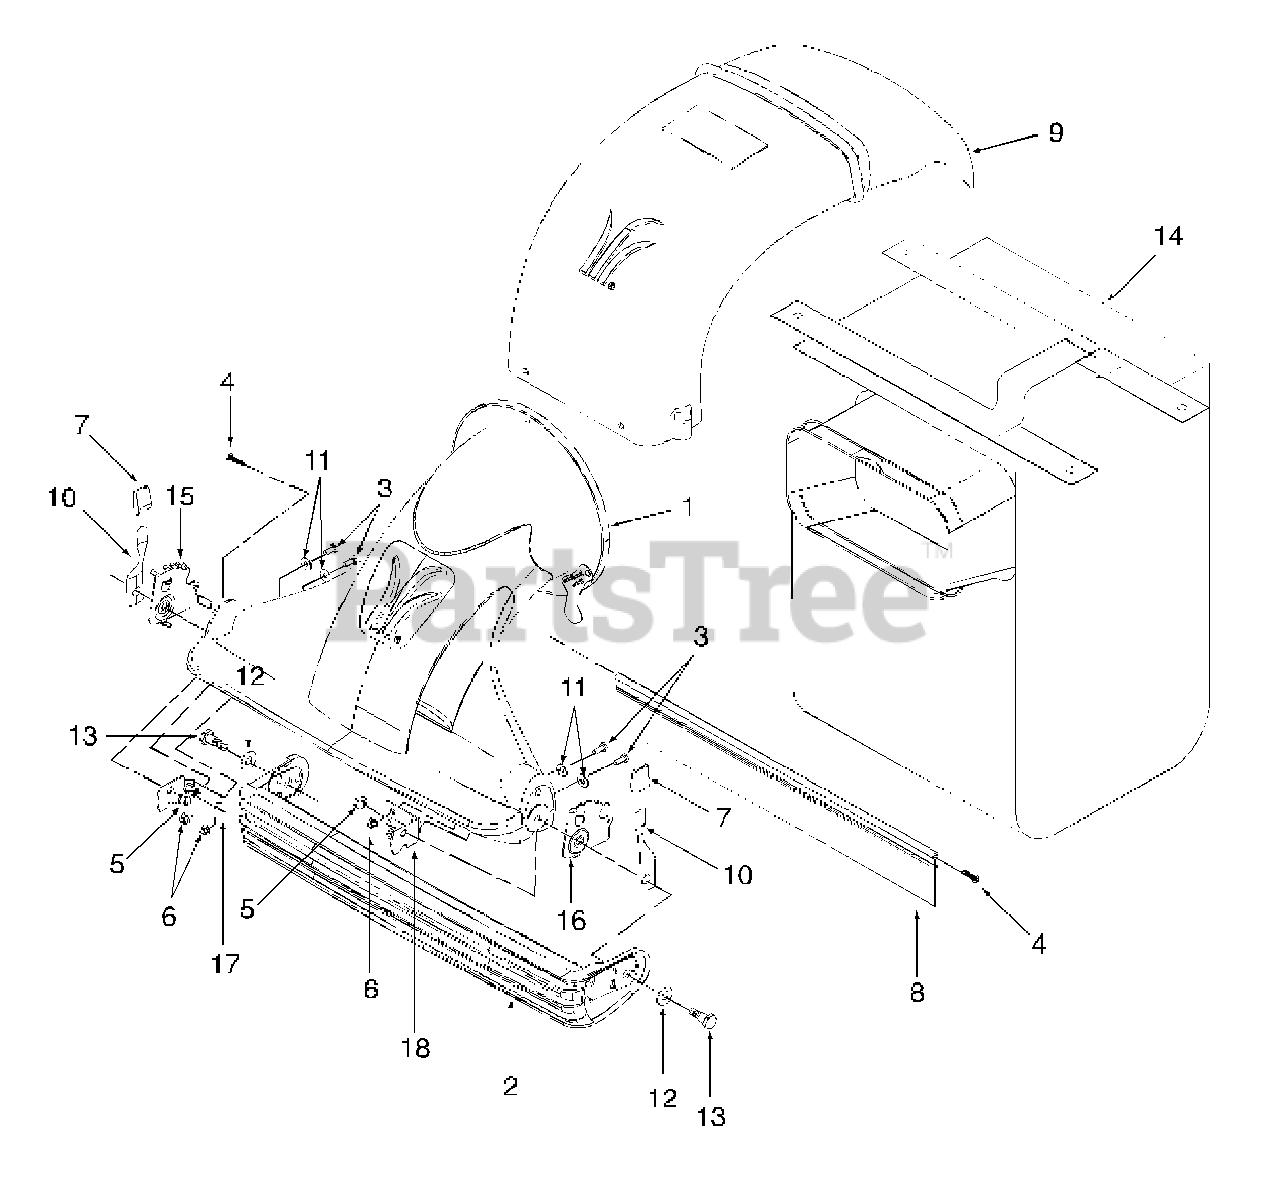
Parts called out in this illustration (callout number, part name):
1	Nozzle Assembly, Black
2	Door Assembly, Black
3	Screw, Hex Cap, 1/4-20 x .625
4	Screw, Truss Hd Tapp
5	Nut, Hex Flange Lock, 3/8-16
6	Nut, Hex Flange Lock, 1/4-20
7	Knob, Height Adj.
8	Flap, Nozzle Rear
9	Discharge Chute
10	Spring Lever
11	Washer, Flat, .28 x .74 x .06
12	Washer, Flat, .510 x 1.20 x .060
13	Screw, Shoulder, .50 x .545 x 3/8-16
14	Bag, 3 Bushel
15	Bracket, Door Index RH
16	Bracket, Door Index LH
17	Bracket, Nozzle Reinforcement RH
18	Bracket, Nozzle Reinforcement LH
